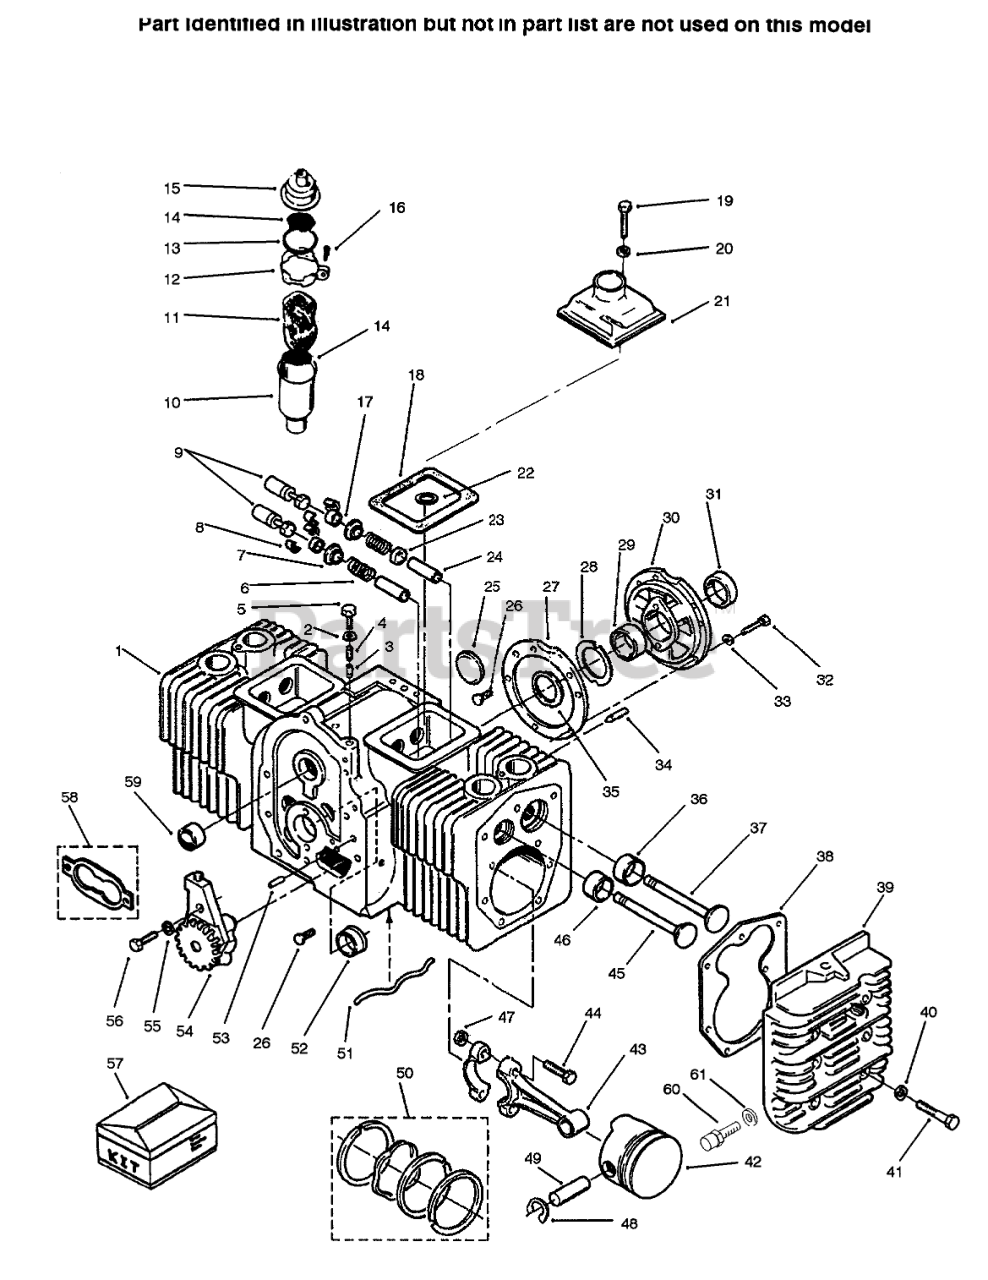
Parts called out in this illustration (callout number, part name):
1	SHORT-BLOCK
2	WASHER
3	PLUNGER
4	SPRING
5	SCREW-HH
6	VALVE SPRING
7	VALVE SPRING RETAINER
8	VALVE SPRING LOCK
9	TAPPET
10	TUBE-BREATHER
11	FILTER
12	Clamp
13	SEAL - O-RING
14	SCREEN-BREATHER TUBE
15	BREATHER-CAP AND VALVE
16	SCREW-TAPPING, ROUND HEAD
17	VALVE CAP
18	GASKET
19	HHCS 1/4-20 X 1 3/4
20	WASHER
21	VALVE-COVER L.H.
22	WASHER-FLAT
23	VALVE STEM SEAL
24	EXHAUST VALVE GUIDE
26	PIN-DRIVE
27	GASKET
29	BEARING KIT (STANDARD SLEEVE)
30	PLATE-BEARING, REAR
32	HEX HD CAPSCREW
33	WASHER-LOCK
33	WASHER-FLAT
34	SCREW-SET
35	WASHER
36	STD INSERT
37	INTAKE VALVE
38	GASKET
39	CYL RS HEAD
40	WASHER
41	Screw-HH
42	STD PISTON KIT
43	CONNECTING ROD W/NUT
45	EXHAUST VALVE
46	STD INSERT
48	Piston Pin
49	PISTON PIN
50	RING/PISTON KIT
51	OIL TUBE
52	KIT-BEARING, SLEEVE
53	PIN-GEAR COVER
55	WASHER-FLAT
56	SCREW - CAP HEX HEAD
57	ENGINE GASKET KIT
58	GASKET KIT
59	SLEEVE-BEARING
60	HIGH TEMPERATURE
61	WASHER-LOCK EXT TO
